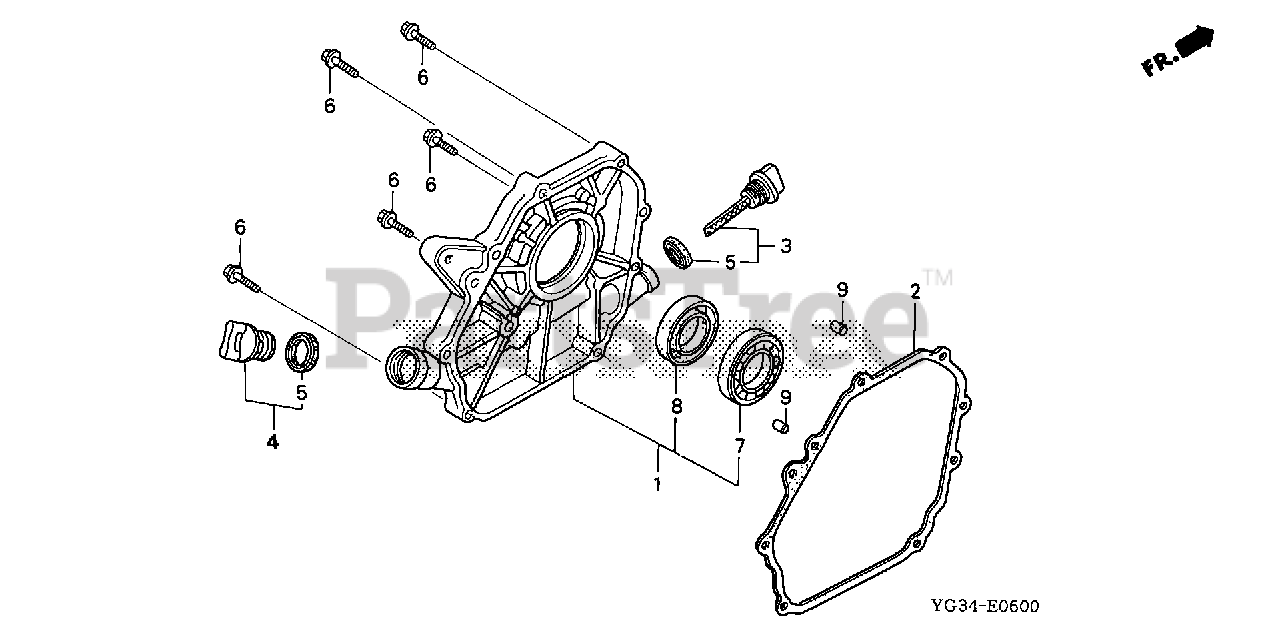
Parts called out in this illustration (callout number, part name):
1	COVER ASSY., CRANKCASE
2	GASKET, CASE COVER (NON-ASBESTOS)
3	CAP ASSY., OIL FILLER
4	CAP ASSY., OIL FILLER
5	GASKET, OIL FILLER CAP
6	BOLT, FLANGE (8X32)
7	BEARING, RADIAL BALL (6205)
8	OIL SEAL (25X41X6)
9	PIN A, DOWEL (8X14)
